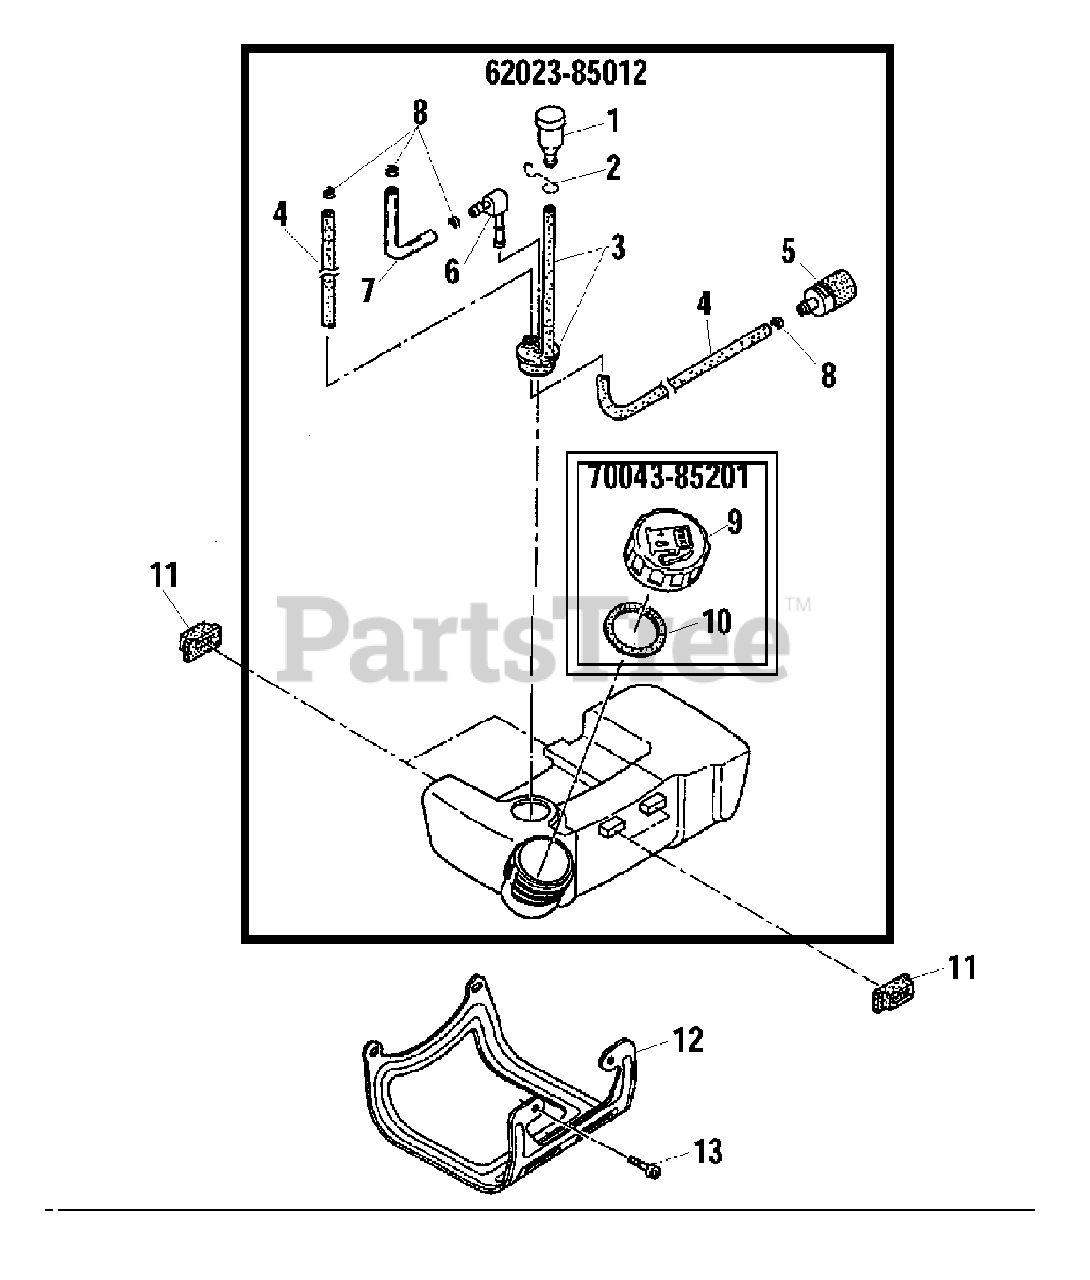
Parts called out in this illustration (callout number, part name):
1	VENT, FUEL TANK
2	HOLDER, VENT
3	VENT PIPE ASSY
4	PIPE - FUEL
5	FILTER, FUEL
6	CONNECTOR, PIPE
7	PIPE - RETURN
8	RING, RETAINING - 6
9	CAP, FUEL
10	GASKET, CAP
11	CUSHION, TANK
12	GUARD, FUEL TANK
13	SCREW - 5X12
62023-85012	FUEL TANK ASSY
70043-85201	CAP ASSY
